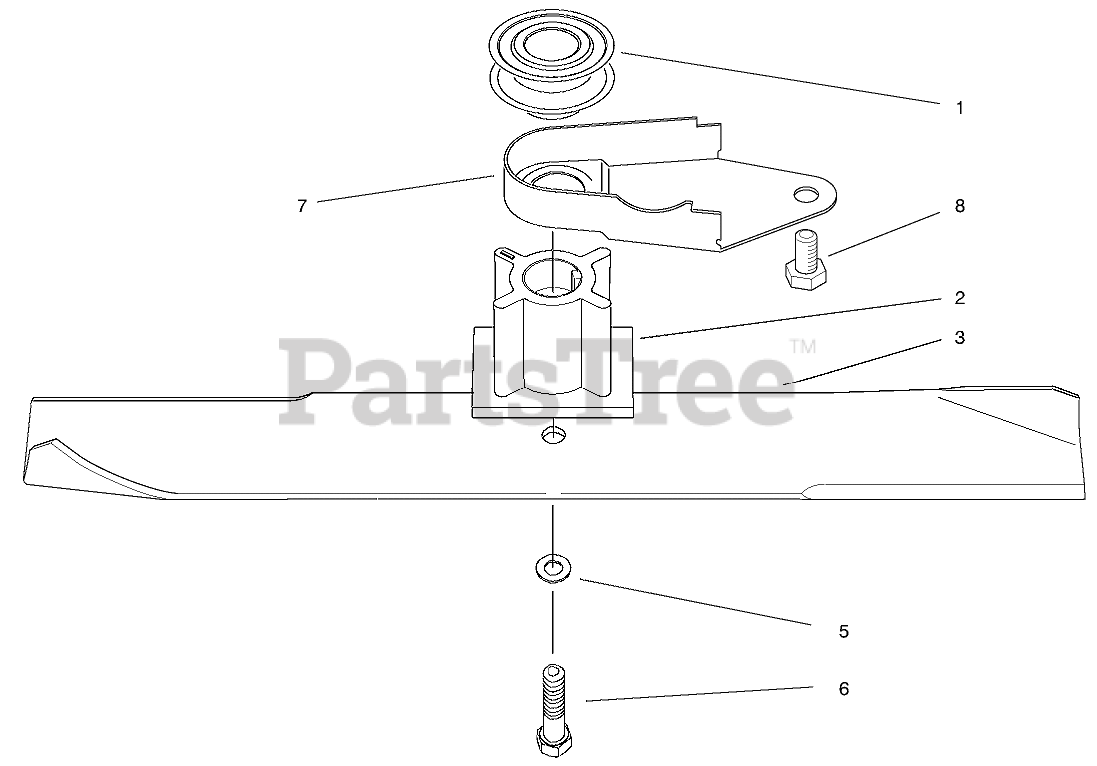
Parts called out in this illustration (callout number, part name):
1	BLADE RETAINER - 25 MM
2	BOLT-BLADE
3	WASHER-LOCK
4	Blade
5	Stiffener Blade
